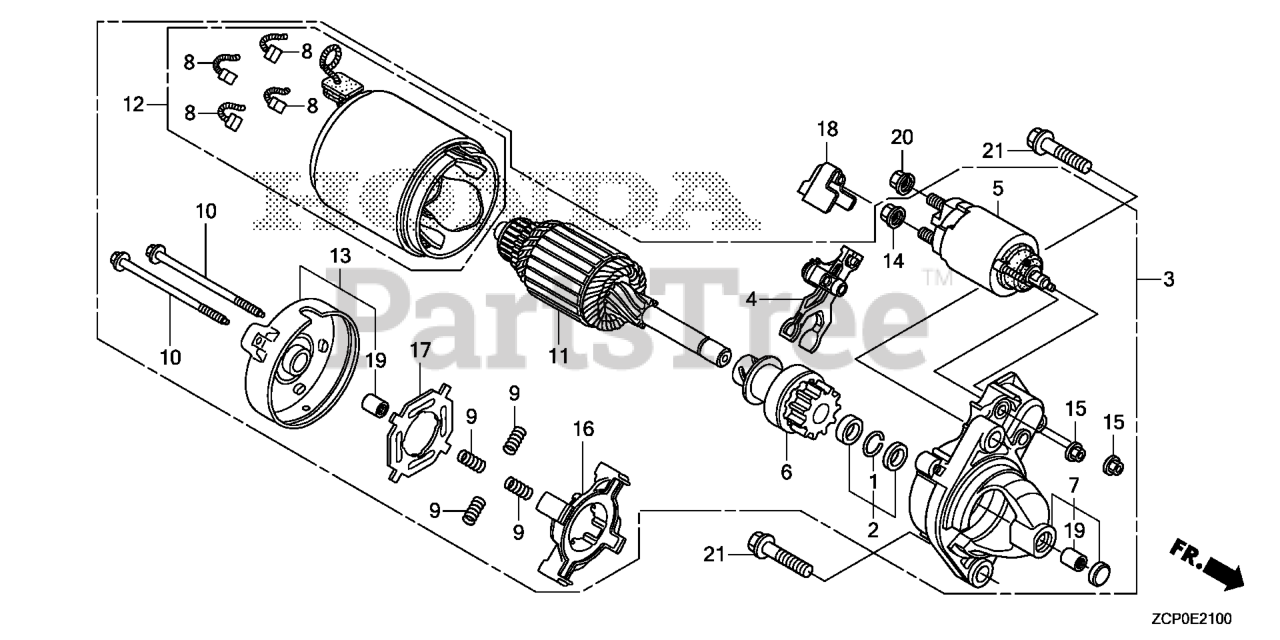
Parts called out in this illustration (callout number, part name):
1	RING, SNAP (DENSO)
2	COLLAR SET, CLUTCH STOP
3	STARTER MOTOR ASSY.
4	LEVER, PINION DRIVE
5	SWITCH ASSY., MAGNET
6	CLUTCH, OVERRUNNING
7	HOUSING, DRIVE SIDE
8	BRUSH
9	SPRING, BRUSH
10	BOLT, THROUGH
12	YOKE
13	FRAME, COMMUTATOR END
14	NUT, HEX. (8MM)
15	NUT, FLANGE (5MM)
16	HOLDER, BRUSH
17	INSULATOR, BRUSH HOLDER
18	COVER, TERMINAL
19	BEARING A
20	NUT-WASHER (8MM)
21	BOLT, FLANGE (10X40)
